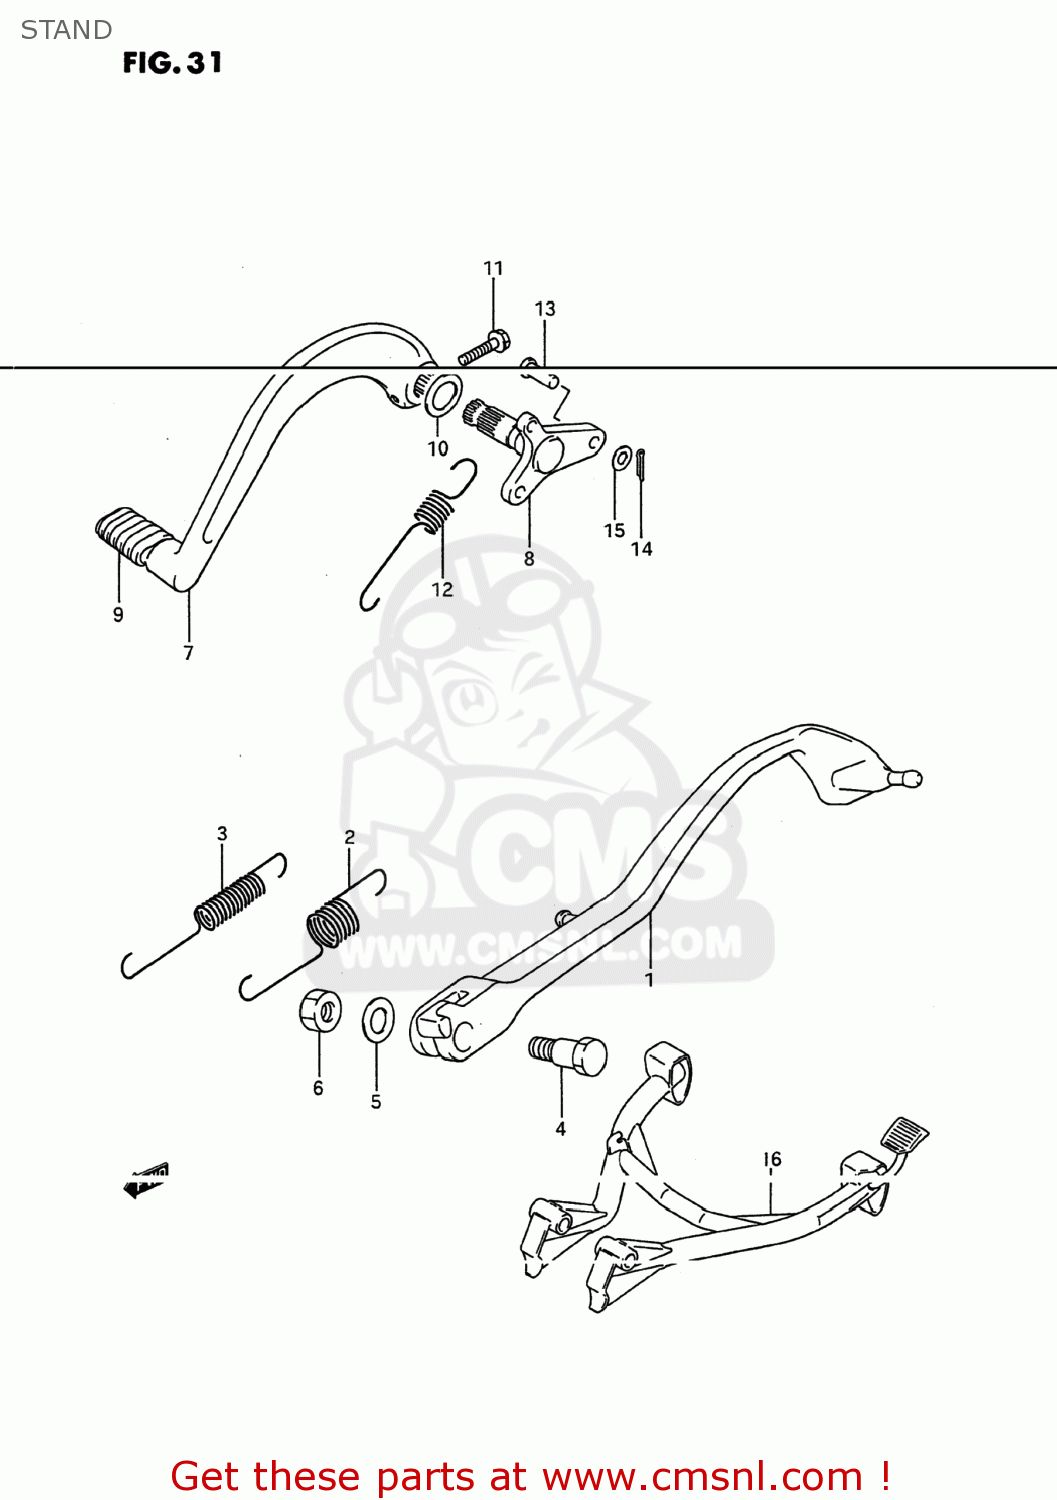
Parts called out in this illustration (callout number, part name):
1	STAND,SIDE
2	SPRING
3	SPRING
4	BOLT(10X38)
5	SHIM
6	NUT
7	PEDAL,BRAKE
8	BOSS,BRAKE ROD
9	RUBBER,BRAKE PEDAL
10	WASHER,BRAKE PEDAL
11	BOLT
12	SPRING
13	PIN
14	PIN
15	WASHER
16	STAND SET,CENTER
